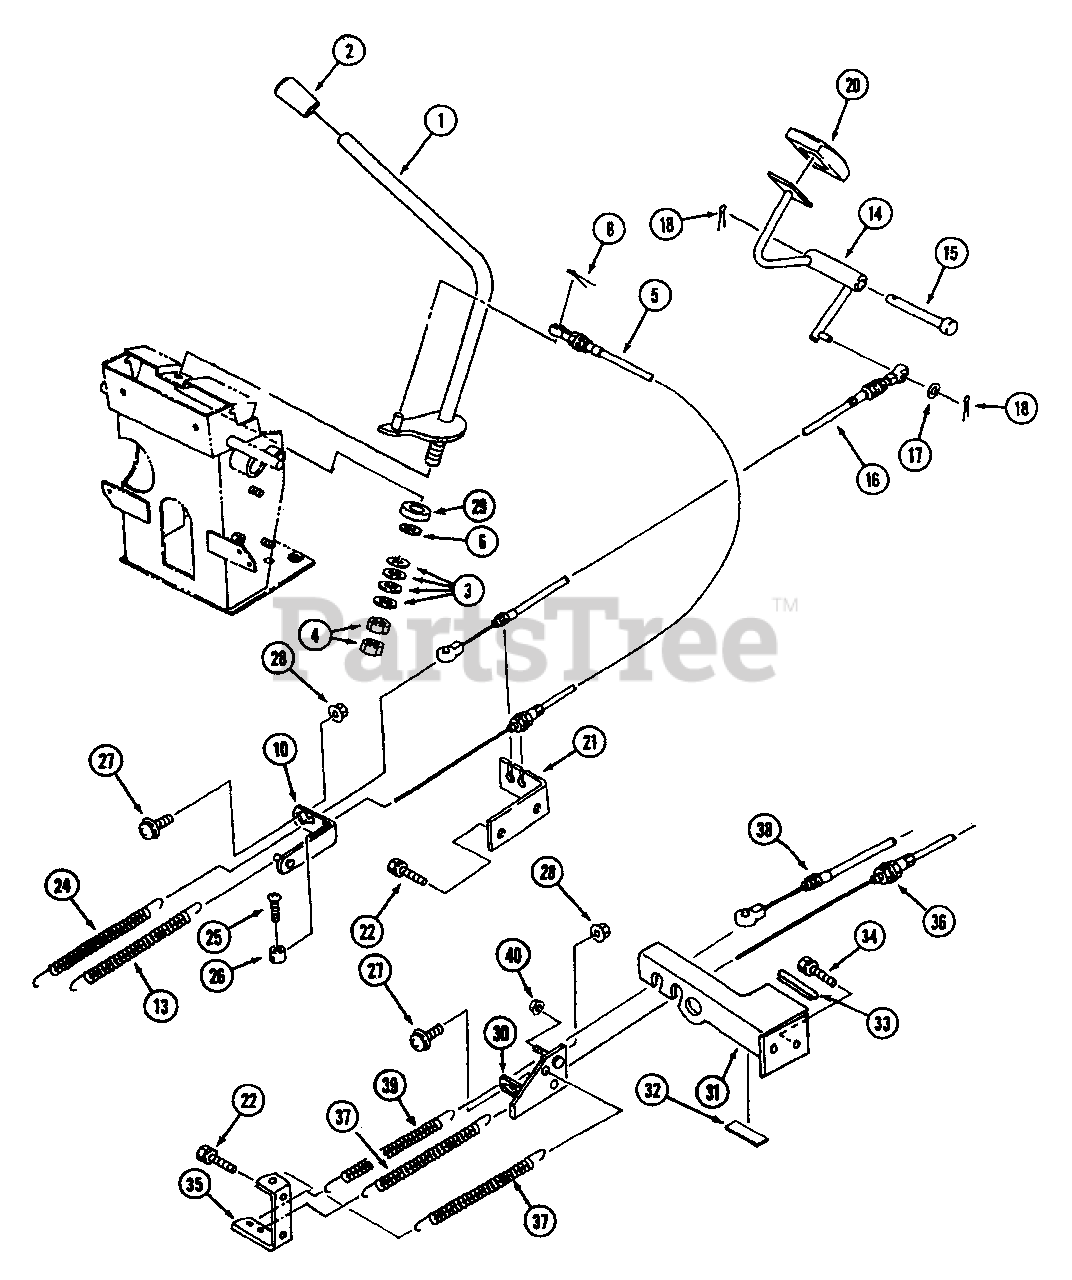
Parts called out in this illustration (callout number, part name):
1	Lever, Accel.
5	Wire, Accelerator
6	Liner
8	Pin, Split
10	Joint
13	Spring
14	Pedal, Accel.
16	Wire, Accelerator
18	Pin, Split
21	Plate
24	Spring
25	Screw
26	Nut
29	Lining, Brake
36	Wire, Accelerator
38	Wire, Accelerator
